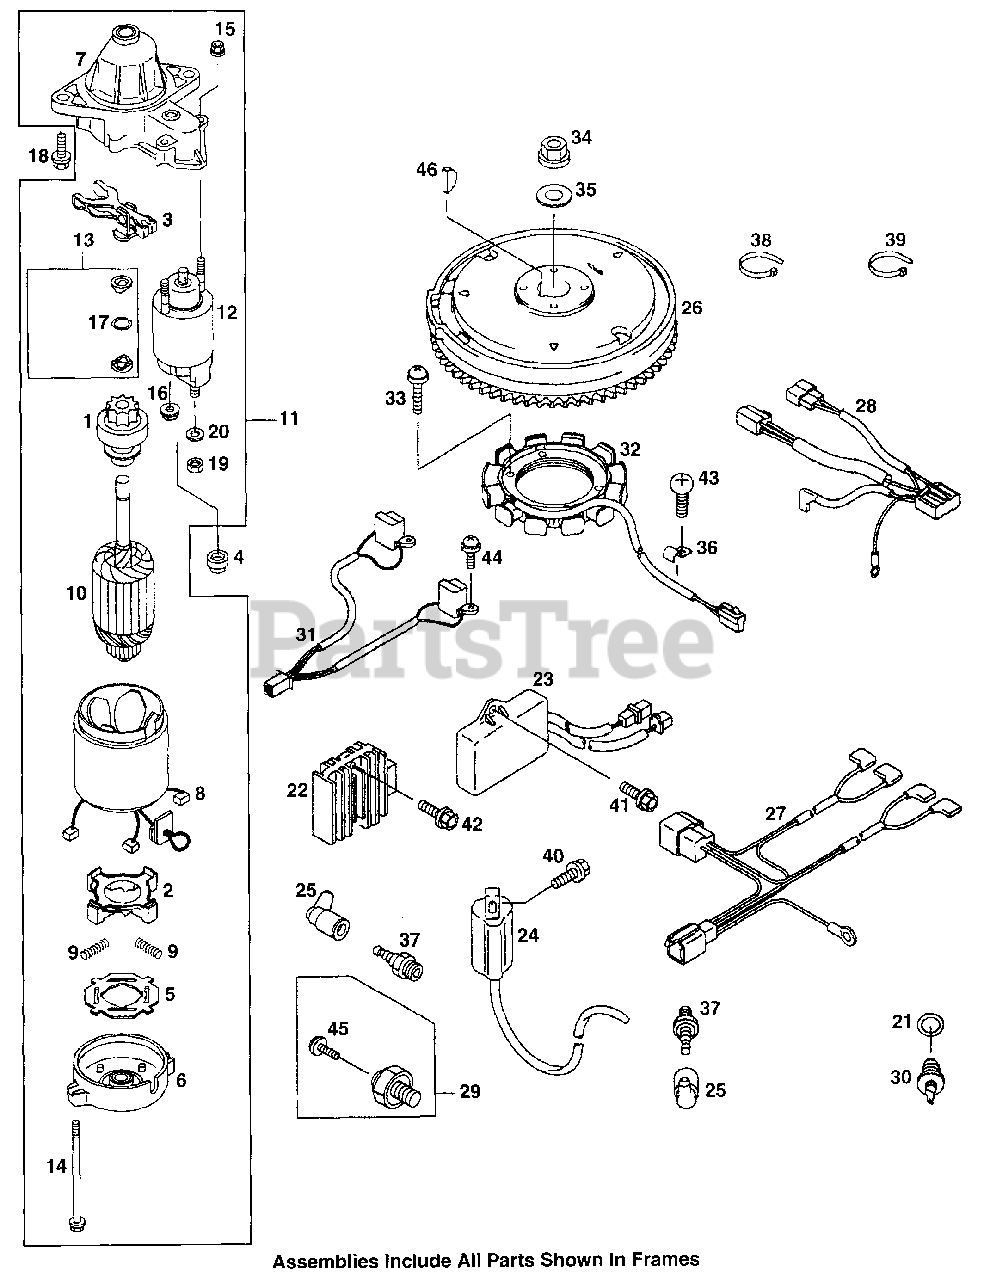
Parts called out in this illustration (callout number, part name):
1	Clutch Assembly
6	Cover Assembly
7	Cover Assembly
11	Electric Starter
12	Switch
18	Flanged Bolt
20	Spring Washer
22	Voltage Regulator
23	Igniter
24	Ignition Coil
25	Spark Plug Cap
26	Flywheel Assembly
28	Harness
29	Switch
31	Pulsing Coil
32	Charging Coil
37	Spark Plug, (NGK - BMR6A)
40	Flanged Bolt
41	Flanged Bolt
42	Flanged Bolt
46	Woodruff Key
